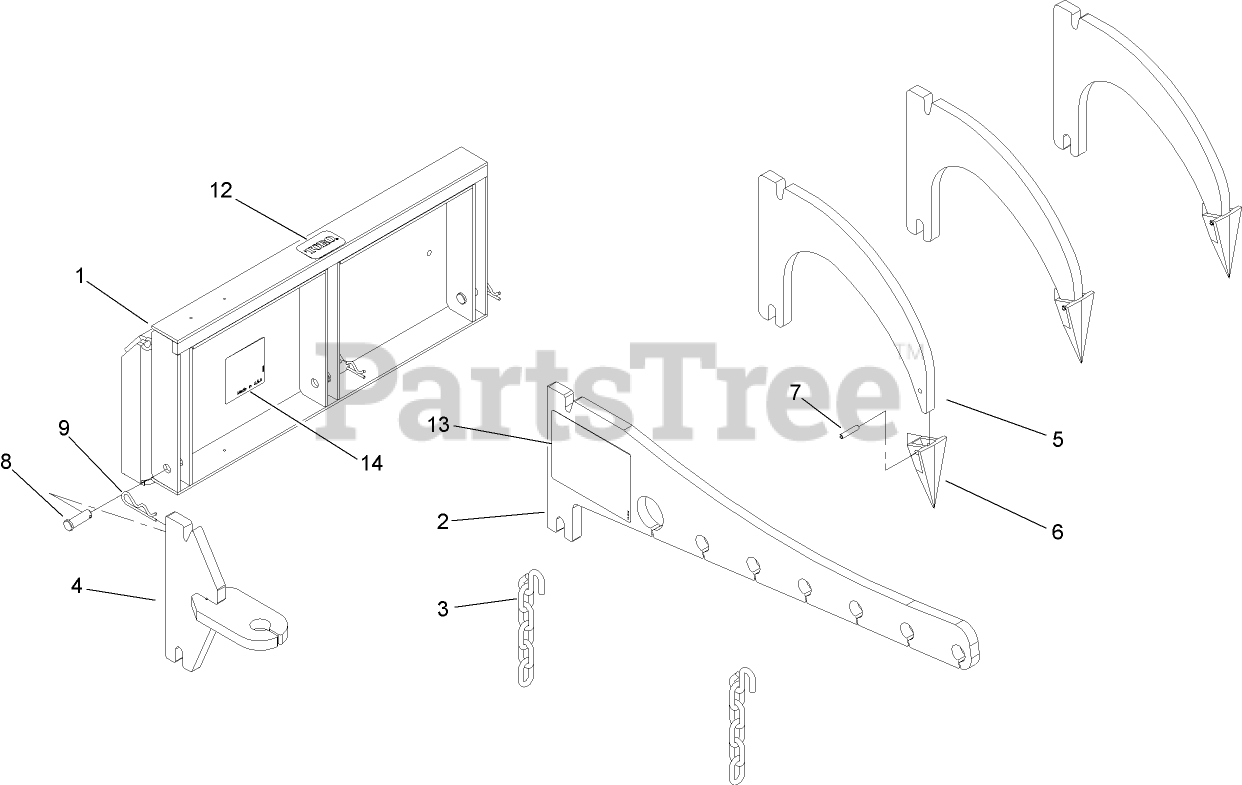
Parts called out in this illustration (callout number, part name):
1	CARRIER TOOL ASM
3	CHAIN-LIFT
4	TOW BAR ASM
5	PLATE-TYNE
6	POINT-Spear
7	PIN-SPRING
8	PIN-CLEVIS
9	PIN-HAIR
12	Decal
13	DECAL-RATING, LOAD
14	DECAL
